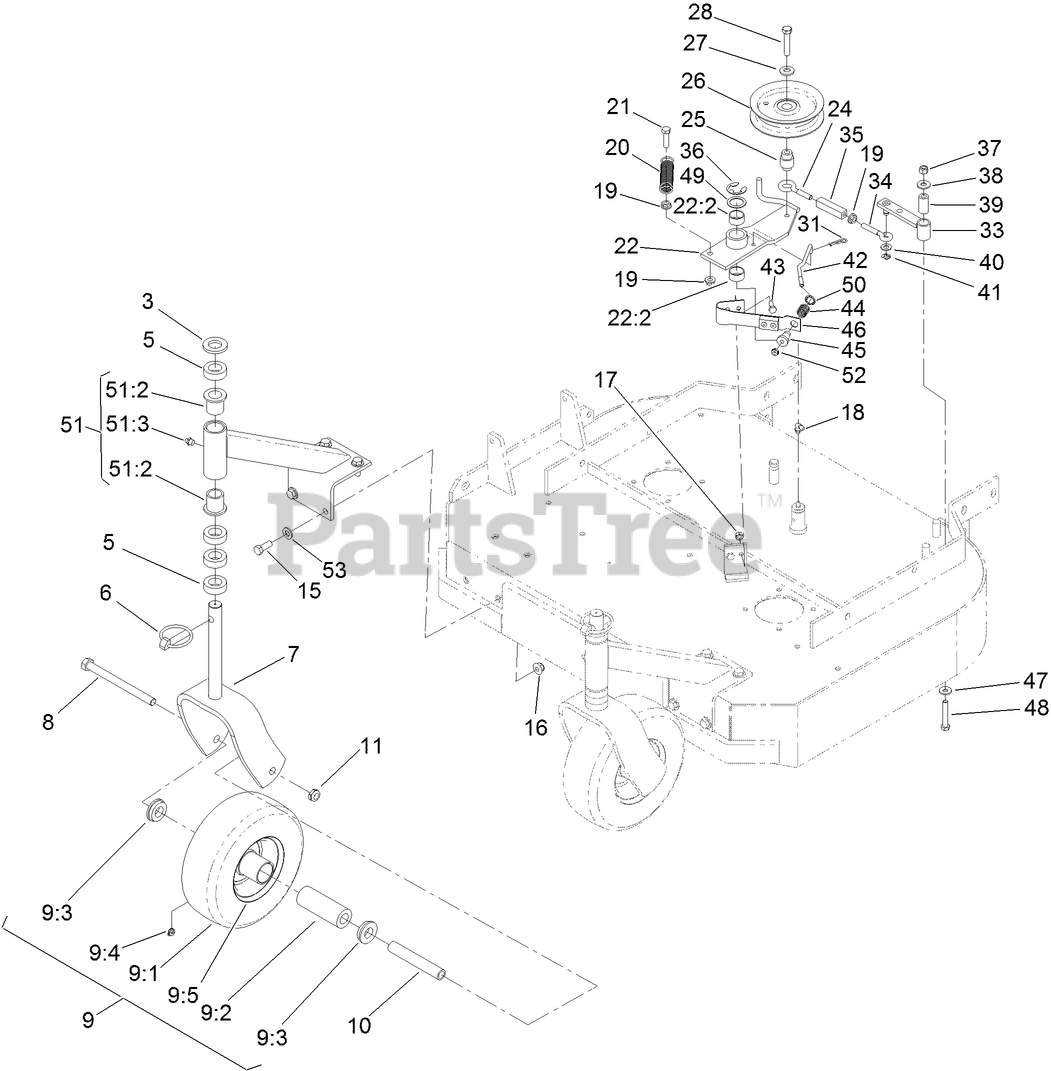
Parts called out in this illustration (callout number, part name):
3	WASHER-FLAT
5	SPACER-CASTER
7	FORK-CASTER
8	SCREW-HH
9	WHEEL AND TIRE ASM
9:1	TIRE
9:2	BEARING
9:3	BUSHING
9:4	FITTING-GREASE
9:5	WHEEL
10	SPACER
11	NUT-HEX
15	SCREW-HH
16	NUT-HF, NI
17	NUT-LOCK, NI
18	FITTING-GREASE, 90 DEG
19	NUT-HF
20	SPRING-EXTENSION
21	SCREW-HH, SPECIAL
22	IDLER ARM ASM
22:2	SLEEVE-BEARING
24	EYEBOLT-THREAD, LH
25	BUSHING-ENGAGEMENT
26	PULLEY-IDLER, FLAT
27	WASHER-BELLEVILLE
28	SCREW-HH
31	PIN-COTTER
33	ARM-ASSIST, 32/36
34	EYEBOLT-THREAD, RH
35	BODY-TURNBUCKLE
36	RING-RETAINING, EXT
37	NUT-LOCK, NI
38	WASHER-FLAT
39	TUBE-PIVOT
40	WASHER-PLAIN
41	RING-RETAINING, EXT
42	ROD-BRAKE
43	SCREW-HH
44	SPRING-COMPRESSION
45	SPACER-FLANGED
46	PAD AND SPRING ASM
47	WASHER-SPRING
48	SCREW-HH
49	WASHER-SPINDLE
50	RING-PUSH ON
51	SUPPORT ASM
51:2	BEARING-FLANGED
51:3	FITTING-GREASE
52	NUT-LOCK, NI
53	WASHER-FLAT
